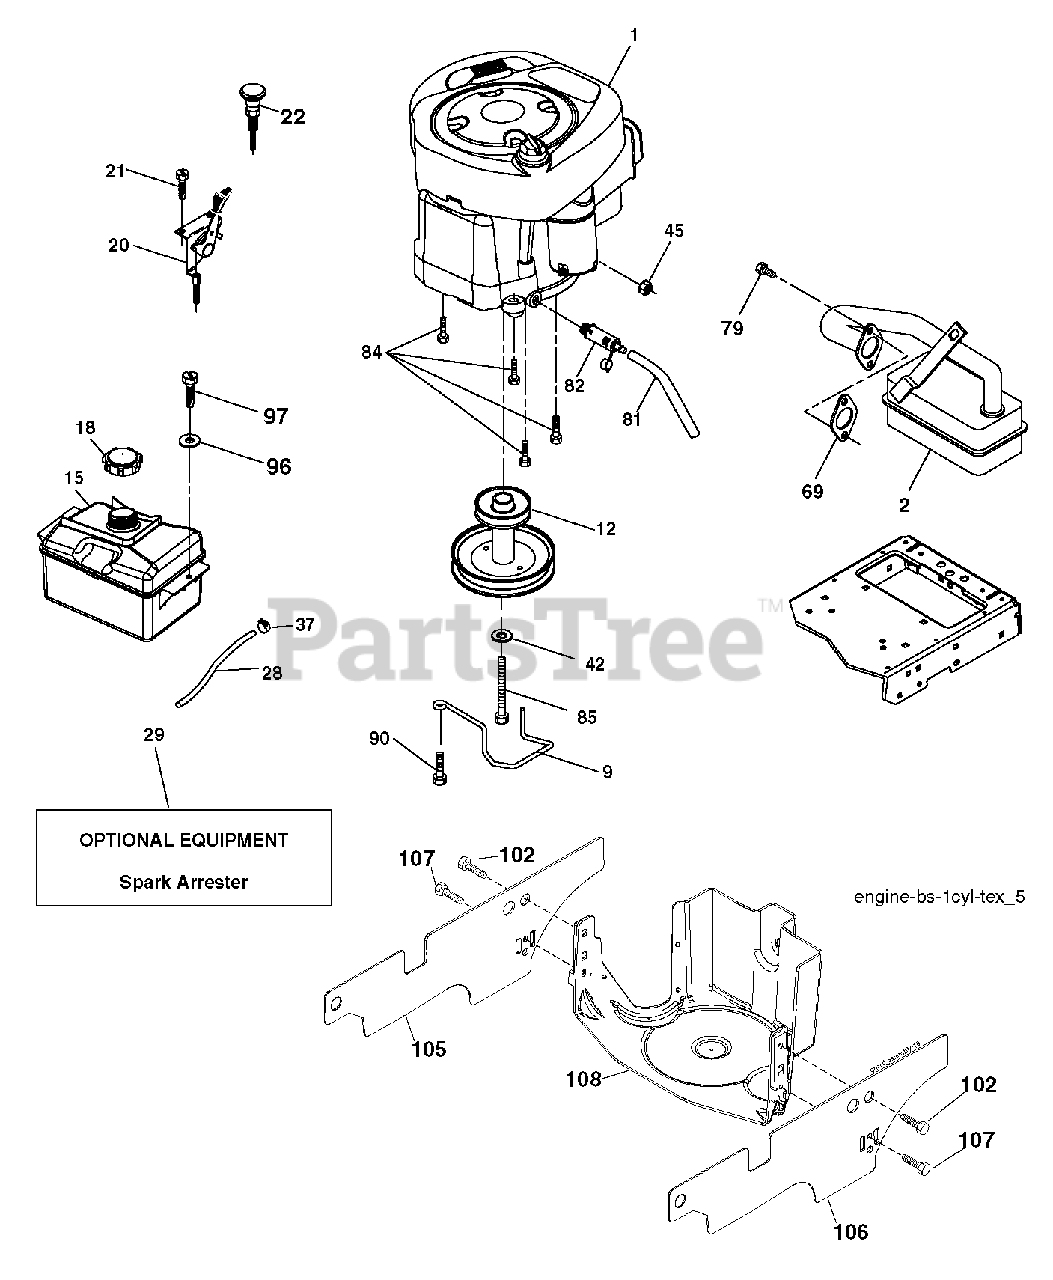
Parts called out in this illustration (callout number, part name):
9	KEEPER.BELT.ENGINE.3.25
12	PULLEY ENGINE
15	TANK FUEL FRT 1.5 GAL
18	FUEL CAP
20	CONTROL.TH/CK.C.
21	SCREW
28	LINE.FUEL.20
29	ARRESTER SPARK (OPTIONAL)
37	HOSE CLAMP
42	LOCKWASHER
45	NUT
69	REPL BY 532 27 22-93
79	SCREW.SOCKET HD.5/16-1
81	TUBE, DRAIN OIL ASM.
82	PLUG DRAIN OIL EASY
84	SCREW.3/8-16
85	BOLT HEX 7/16-20X4-1/4"
90	SCREW 3/8-16X1
97	SCREW HEXWSHR 1/4-20X3/4
102	SCREW
107	SCREW.1/4-20X5/8
